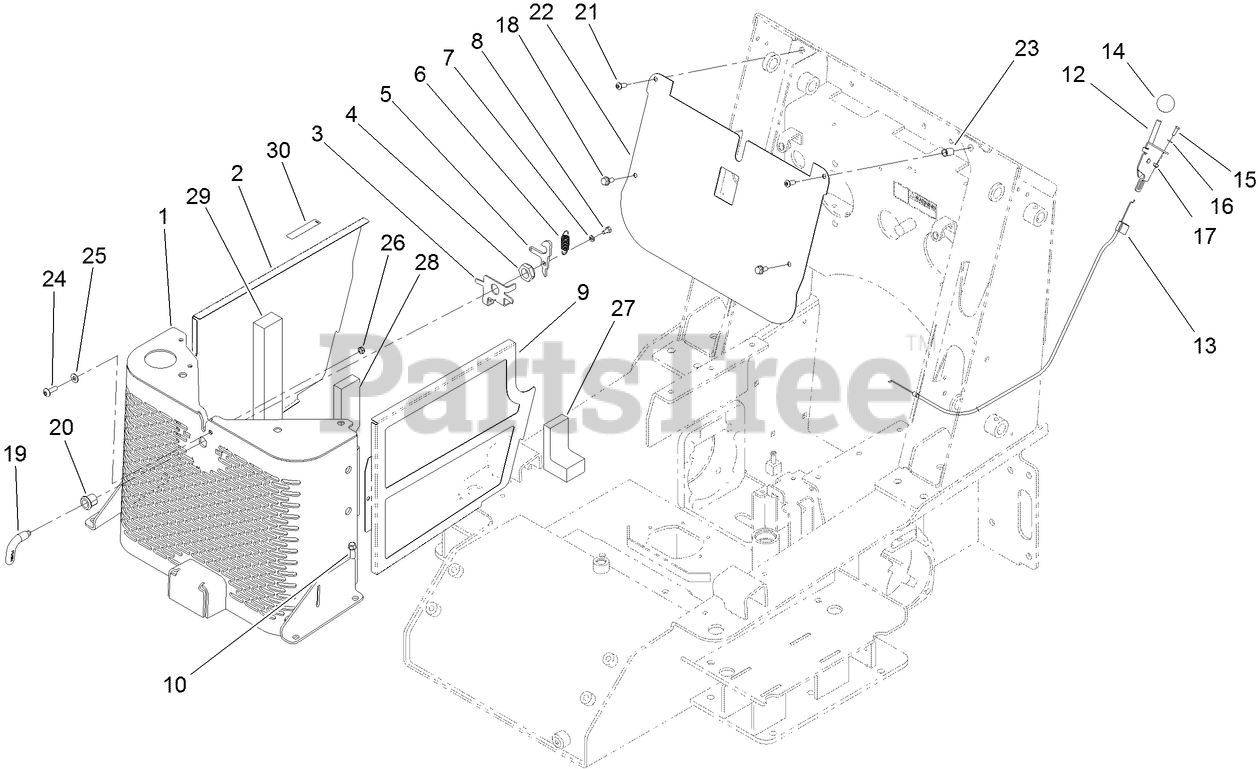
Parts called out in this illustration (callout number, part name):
1	GRILL ASM
2	RH SIDE PANEL
3	BRACKET-LATCH
4	NUT-LOCK, NI
5	CAM-LATCH
6	SPRING
7	WASHER-LOCK
8	SCREW-HH
9	LH SIDE PANEL
10	SCREW-TAPTITE
12	LEVER-CONTROL
13	CABLE-THROTTLE
16	WASHER-FLAT
17	NUT-KEPS
18	SCREW-HHF
19	HANDLE-LATCH
20	HOUSING-LATCH
21	SCREW-HSBH
22	BAFFLE-ELECTRICAL
23	INSERT-THREADED
24	SCREW-PTH
25	WASHER-FLAT
26	NUT-LOCK, NI
27	SEAL-FOAM
28	SEAL-FOAM
29	SEAL-FOAM
30	DECAL-WARNING, FAN
